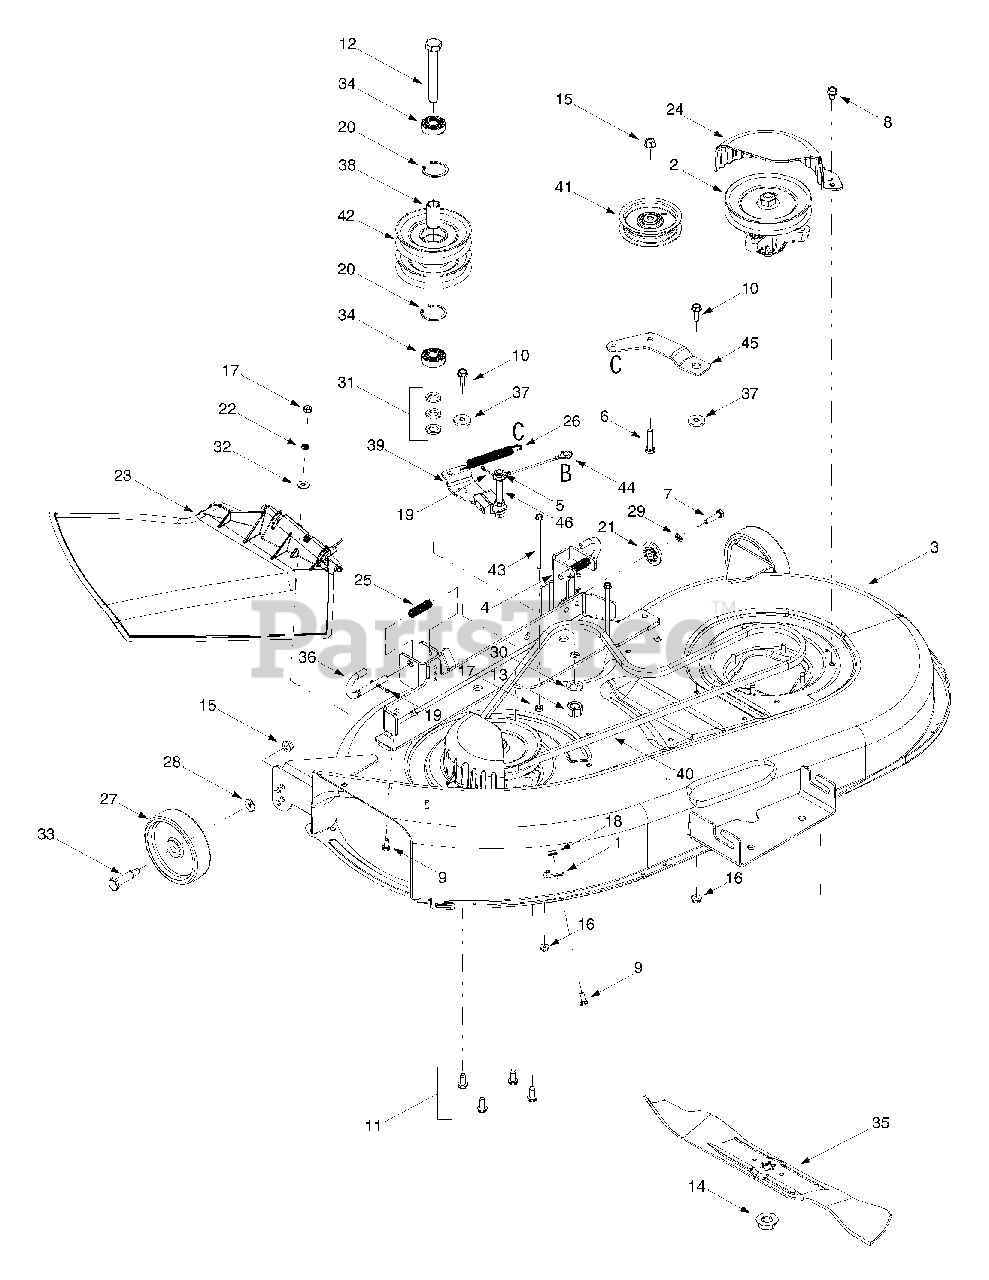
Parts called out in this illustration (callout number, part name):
1	Retainer Hook
2	Spindle Assembly, 5.75 Dia. w/ Fitting
5	Flat Washer, .385 x .62 x .063
6	Hex Cap Screw, 1/4-20 x 1.5
7	Hex Cap Screw, 5/16-18 x 1.25
8	Self-tapping Screw, 5/16-18 x .625
9	Hex Cap Screw, 1/4-20 x .62
10	Hex Head Washer Screw, 5/16-18 x .875
11	Self-tapping Screw, 5/16-18 x .75
12	Hex Cap Screw, 5/8-18 x .875
13	Hex Nut, 5/8-18
14	Hex Flange Nut, 5/8-18
15	Flange Lock Nut, 3/8-16
16	Flange Lock Nut, 5/16-18
17	Hex Nut, 1/4-20
18	Hex Flange Lock Nut, 1/4-20
19	Cotter Pin, 1/8 x 1.25
20	Internal Snap Ring
21	Deck Adjustment Gear
22	Push Nut. .25 x .5
23	Side Discharge Chute Assembly
24	Belt Cover
25	Compression Spring, .406 x .531 x 1.75
26	Extension Spring, .50 x 4.74
27	Deck Wheel, 5 x 1.38
28	Bell Washer, .401 x .87 x .063
29	Lock Washer, 5/16
30	Lock Washer, 5/8
31	Flat Washer, .64 x 1.0 x .12
32	Bell Washer, .265 x .75 x .062
33	Shoulder Screw, .498 x 1.53
34	Bearing, .625 x 1.574 x .470
35	Three-in-one Blade, Star Center, 21.23"
36	Deck Release Pin
37	Shoulder Spacer, .625 x .324
38	Spacer, .635 x .88 x 1.72
39	Deck Brake Assembly
40	Deck Belt
41	Idler Pulley, 3.5
42	Double Pulley, 5.0
43	Self-tapping Screw, 1/4-20 x 4.0
44	Brake Cable, 5.05
46	Pin, 3/8-16, 3/8 x 3.27
